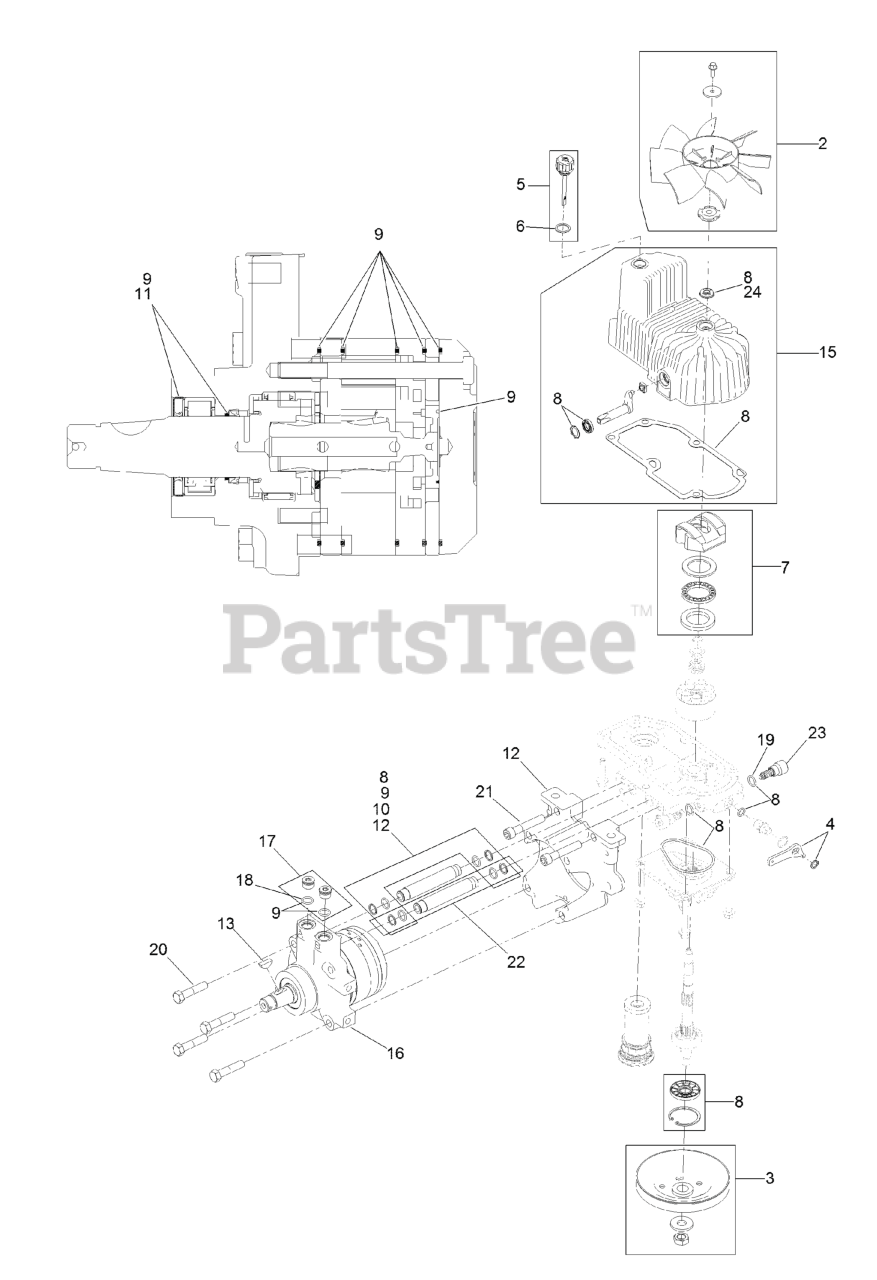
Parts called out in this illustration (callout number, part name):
2	FAN KIT
3	PULLEY KIT
4	HANDLE-BYPASS VALVE, HYDRO
5	DIPSTICK-HYDRO W/GASKET
6	GASKET-DIPSTICK, HYDRO
7	SWASH BLOCK KIT
8	PUMP SEAL KIT
9	MOTOR SEAL KIT
10	TUBE SEAL KIT
11	OUTPUT SHAFT SEAL KIT
12	NOSE CUP-UHT
13	KEY-WOODRUFF
15	HOUSING-HYDRO, LH
16	MOTOR-HYDRAULIC, LH 280CC
17	MAGNETIC PLUGS SERVICE KIT
19	O-RING-CHECK VALVE
20	SCREW HH
21	SCREW-HSH
22	HYDRAULIC TUBE KIT
23	SHOCK VALVE, 16CC HYDRO
24	SEAL-FAN DRIVE
25	16Cc LH Pump Section Kit
26	16Cc LH Rotating Grp Kit
